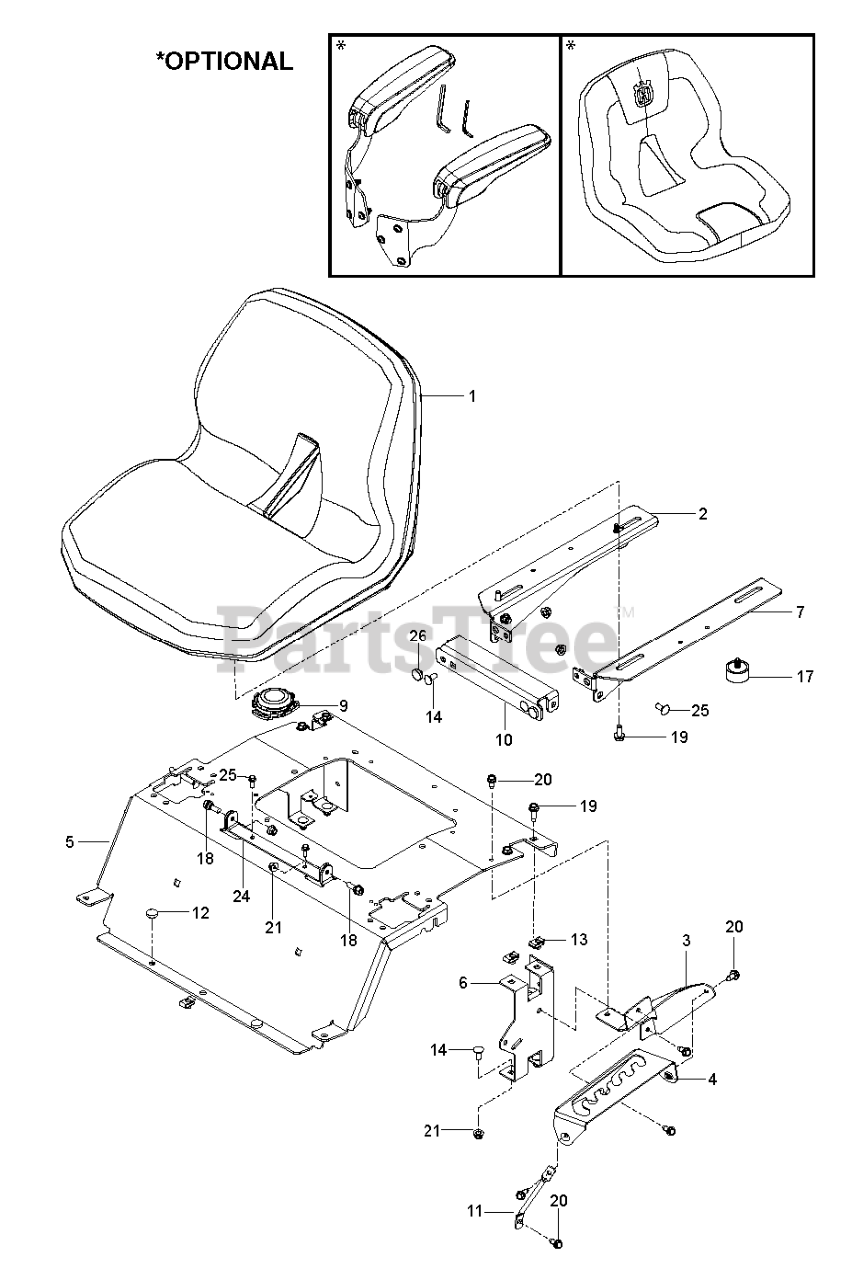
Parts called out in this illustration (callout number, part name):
2	BRACKET SEAT PAN RIGHT BLACK X
3	PLATE.SUPPORT.DECK.LIFT.X431
4	PLATE.DECK.LIFT.X431
5	PLATE SEAT SUPPORT; RZ ORANGE
6	SUPPORT REAR SEAT BLACK
7	BRACKET SEAT PAN LEFT BLACK X4
9	SWITCH.SEAT.DP W/RAMPS
10	BRACKET FRONT SEAT PAN BLACK X
11	SUPPORT.LEG.DECK.LIFT
12	GROMMET.BUMPER
13	U-CLIP 5/16-18 NUT RETAINER
14	BOLT 5/16C X 3/4" CARRIAGE
17	BUMPER 5/16-18
18	BOLT 5/16C X 3/4" CARRIAGE
19	SCREW.THDROL.5/16-18X3/4.TTY
20	BOLT.5/16HEX.WHS.HD
21	5/16-18 NYLOC FLANGE NUT
24	BRACKET.SEAT.REINF.X668
25	SCREW.FLG.LOCKING.1/4-20X.75
26	GROMMET, BUMPER
